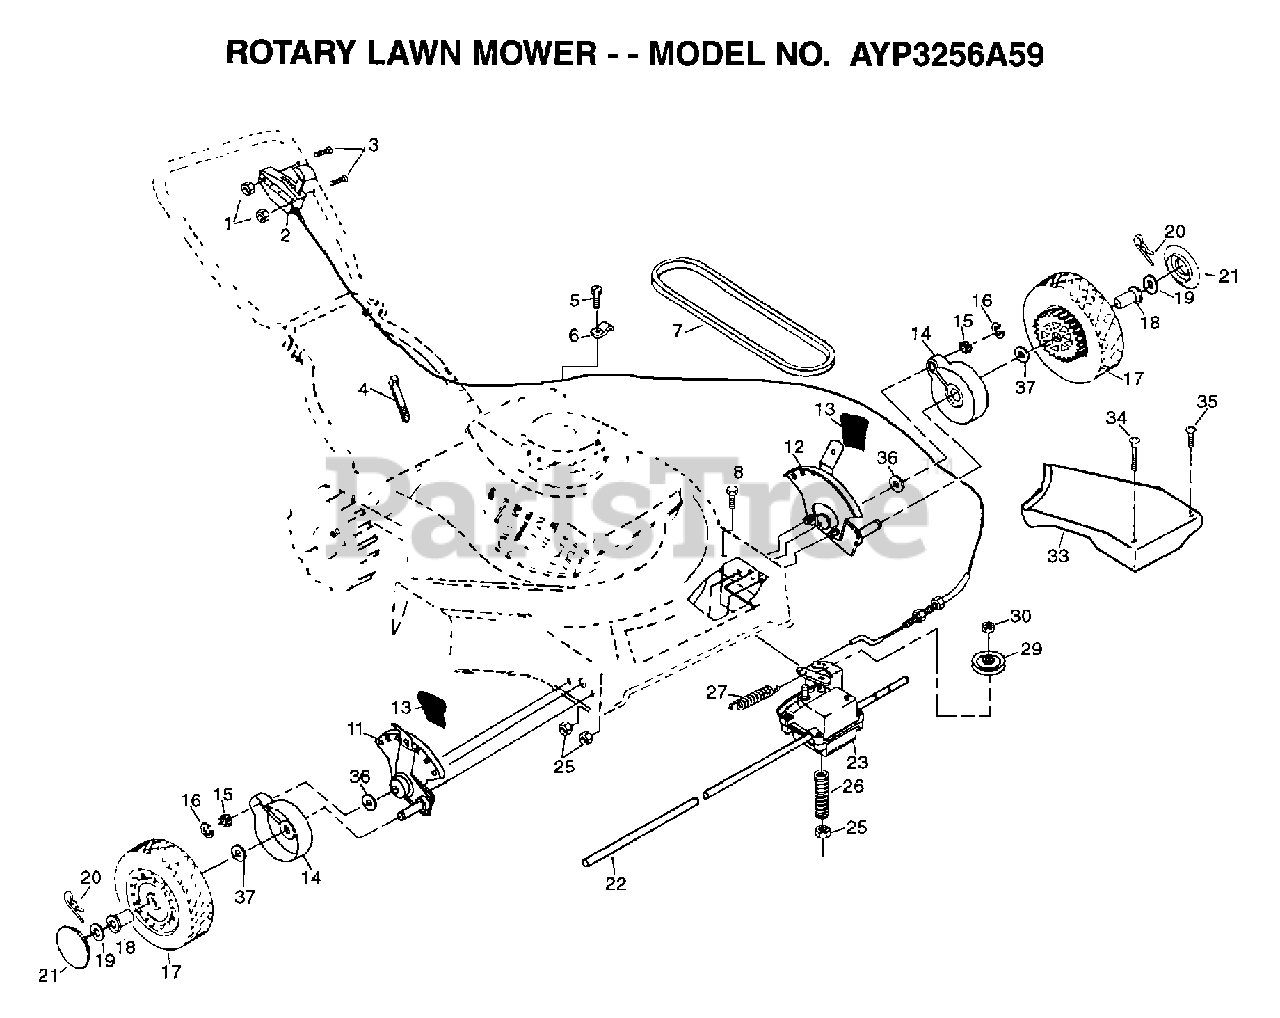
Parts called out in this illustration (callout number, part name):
2	CONTROL.DRIVE
5	TAPPING SCREW
6	GUIDE CLIP PM
8	BOLT.1/4-20X2.0
14	DUST SHROUD PM
15	PINION.GEAR
16	E-RING.7/16.RE.
17	WHEEL.8X2.LP.PR
18	BUSHING.ROUND
19	WASHER
20	RETAINER CLIP PM
21	HUB CAP
22	DRV SHAFT TUBE PM
26	SPRING.TENSION
27	SPRING
29	PULLEY.DRIVEN
30	LOCKNUT
33	COVER DRIVE BLK
36	WASHER PM
37	WASHER FLUT
